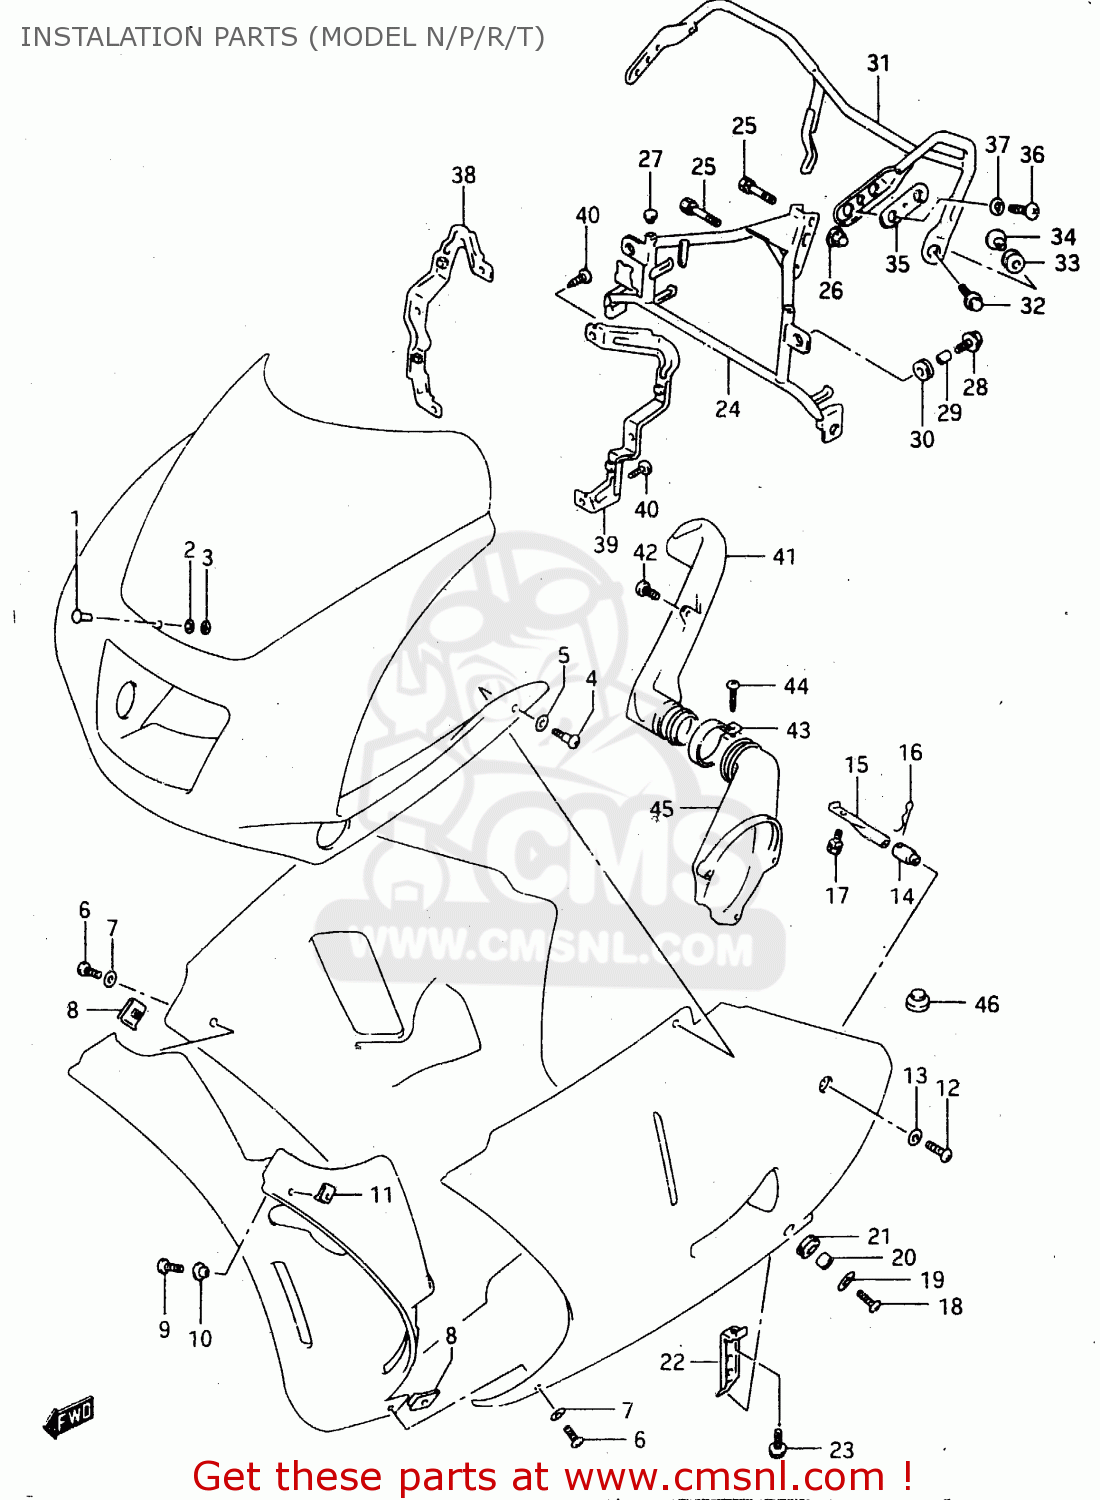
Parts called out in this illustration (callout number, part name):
1	PIN,WINDSCREEN
2	CUSHION
3	NUT
4	SCREW(5X16)
5	WASHER(7X13X0.6)
6	SCREW(5X16)
7	WASHER(7X13X0.6)
8	NUT,RH & CTR UNDER COWLING
9	SCREW
10	WASHER(5.2X14X1.5)
11	NUT
12	SCREW(6X18)
13	WASHER
14	PLUG,UNDER COWL FTG,CTR
15	PIPE,UNDER COWL FTG CTR
16	PIN,UNDER COWLING FITTING PIPE
17	BOLT
18	SCREW(6X18)
19	WASHER(6.5X18X1)
20	SPACER (6.1X9X10)
21	CUSHION
22	BRACKET, UNDER LH
23	BOLT(6X16)
24	BRACE,COWLING
25	BOLT
26	NUT
27	CAP(OD:12)
28	BOLT 6X20
29	SPACER (6.1X9X10)
30	CUSHION
31	BRACE,RR VIEW MIRRORR
32	BOLT 6X20
33	CUSHION
34	WASHER
35	CUSHION,RR VIEW MIRRORR
36	SCREW(6X12)
37	WASHER(6.2X19X1.5)
38	BRACKET,HEADLAMP FIT,R
39	BRACKET,HEADLAMP FIT,L
40	SCREW
41	BODY,AIR DUCT COWL NO.1
42	SCREW
43	CLAMP
44	SCREW
45	BODY,AIR DUCT COWL NO.2
46	CUSHION
